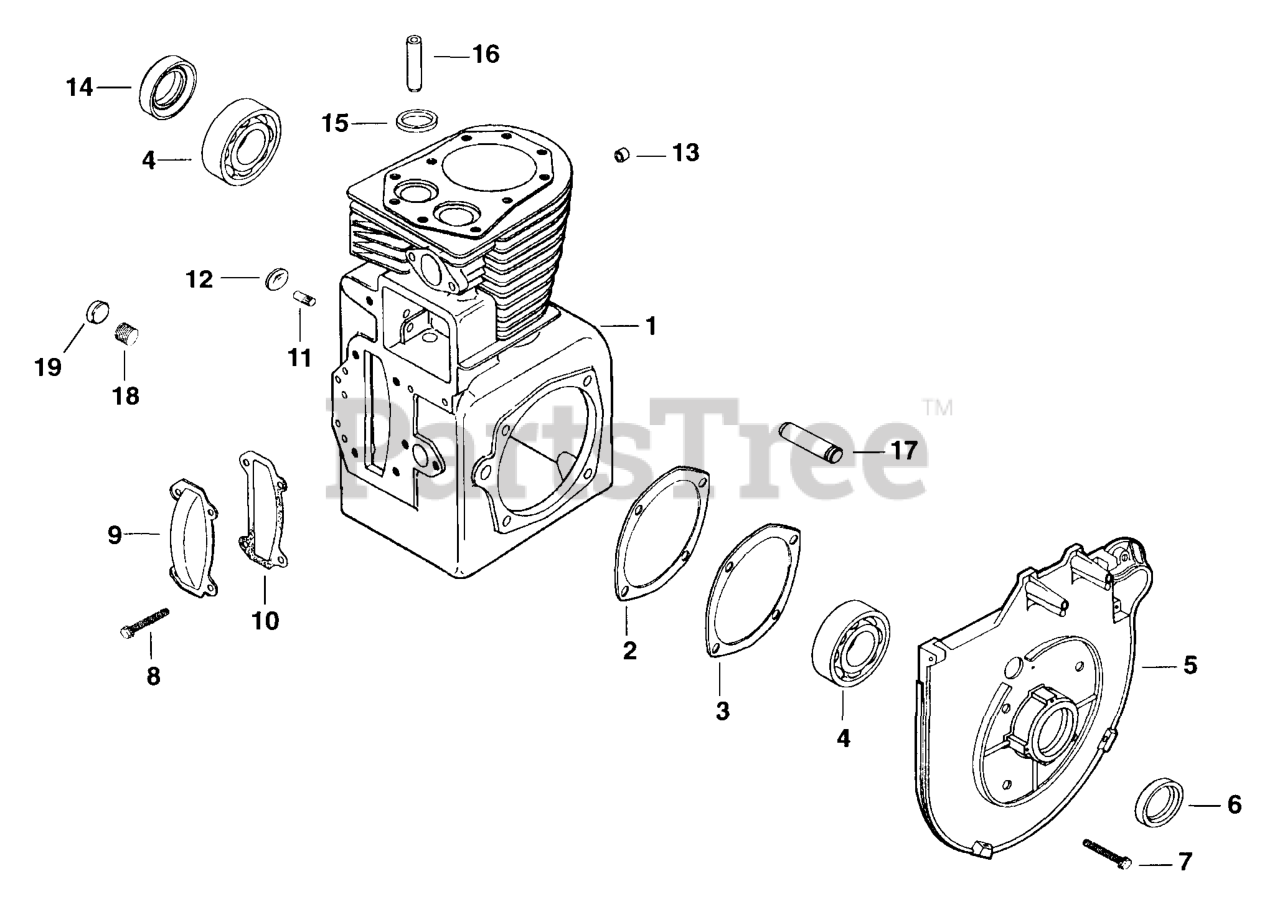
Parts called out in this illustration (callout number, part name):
1	Cylinder Block
3	GASKET, BEARING PLATE - DISCONTINUED
4	BEARING, BALL
5	PLATE, BEARING - DISCONTINUED
6	SEAL, FRONT OIL
7	SCREW, SEMS 3/8-16-X1"
8	SCREW, SEMS 1/4-20-1/2"
9	COVER, CAMSHAFT - DISCONTINUED
10	GASKET, CAMSHAFT COVER
11	SHAFT, GOVERNOR GEAR
12	PLUG, WELCH EXPANSION
13	BEARING
14	SEAL, REAR OIL
16	GUIDE, VALVE - DISCONTINUED
